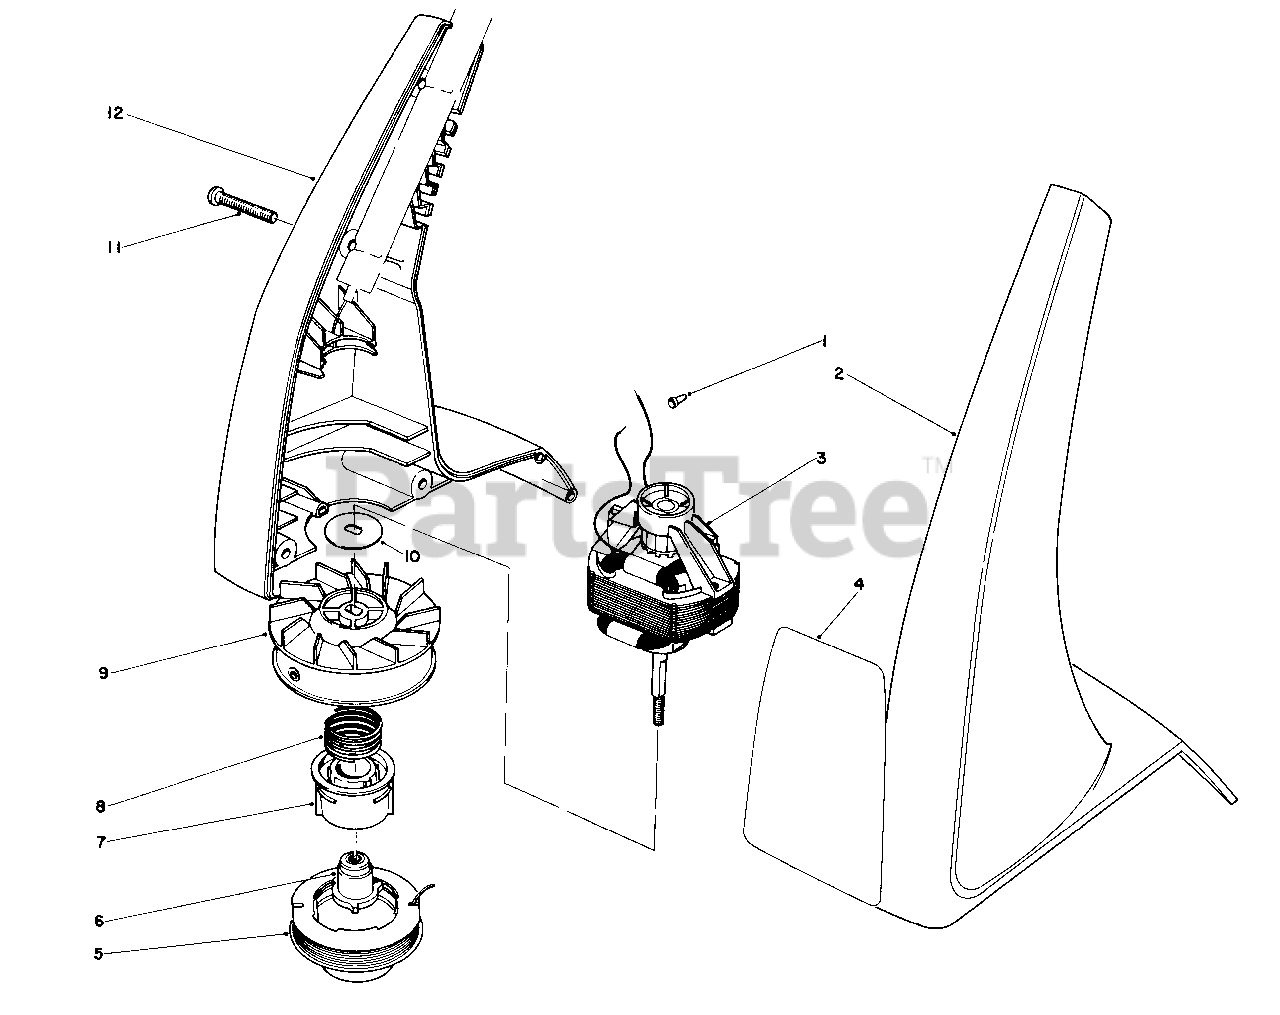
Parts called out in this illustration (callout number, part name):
1	Connector-Wire
2	Housing-L.H.
5	Cutting Line (12' .05 Dia.)
7	Core-Spool
8	Spring-Compression
9	Drum w/Eyelet
10	Washer-Motor
11	Screw
12	Housing-Assembly R.H. (Incl. Ref. #13 & 14)
